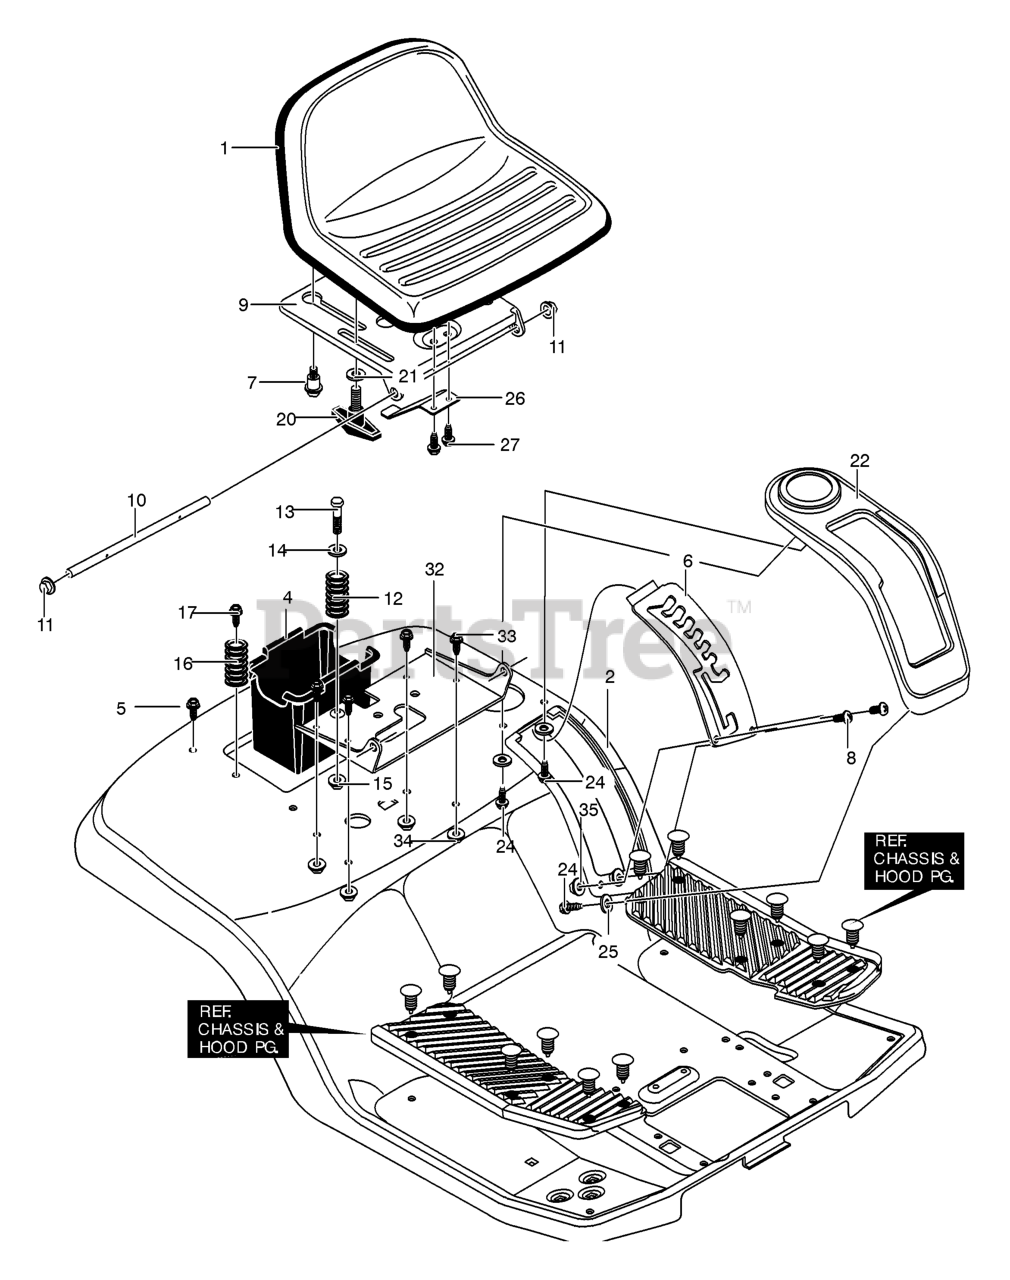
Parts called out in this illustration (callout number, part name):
2	SEAT DECK
4	CONTAINER, BATTERY
5	SCREW, 1/4-20X .63
6	PLATE, LIFT
7	BOLT, SHOULDER
8	SCREW, 10-24X.500
9	SUPPORT, SEAT
10	HINGE, SEAT PIVOT
11	NUT, PUSH CAP
12	SPRING, COMPRESSION
13	BOLT, SHOULDER
14	WASHER, CUP
15	NUT, 1/4-20
16	SPRING, COMPRESSION
20	BOLT, WING
21	Washer
22	COVER, DETENT
25	WASHER
26	SPRING - LEAF
27	SCREW, 1/4-20X.50
32	BRACKET, PIVOT SEAT
33	BOLT, 5/16-18X.75
34	NUT, 5/16-18
35	NUT, #10-24
